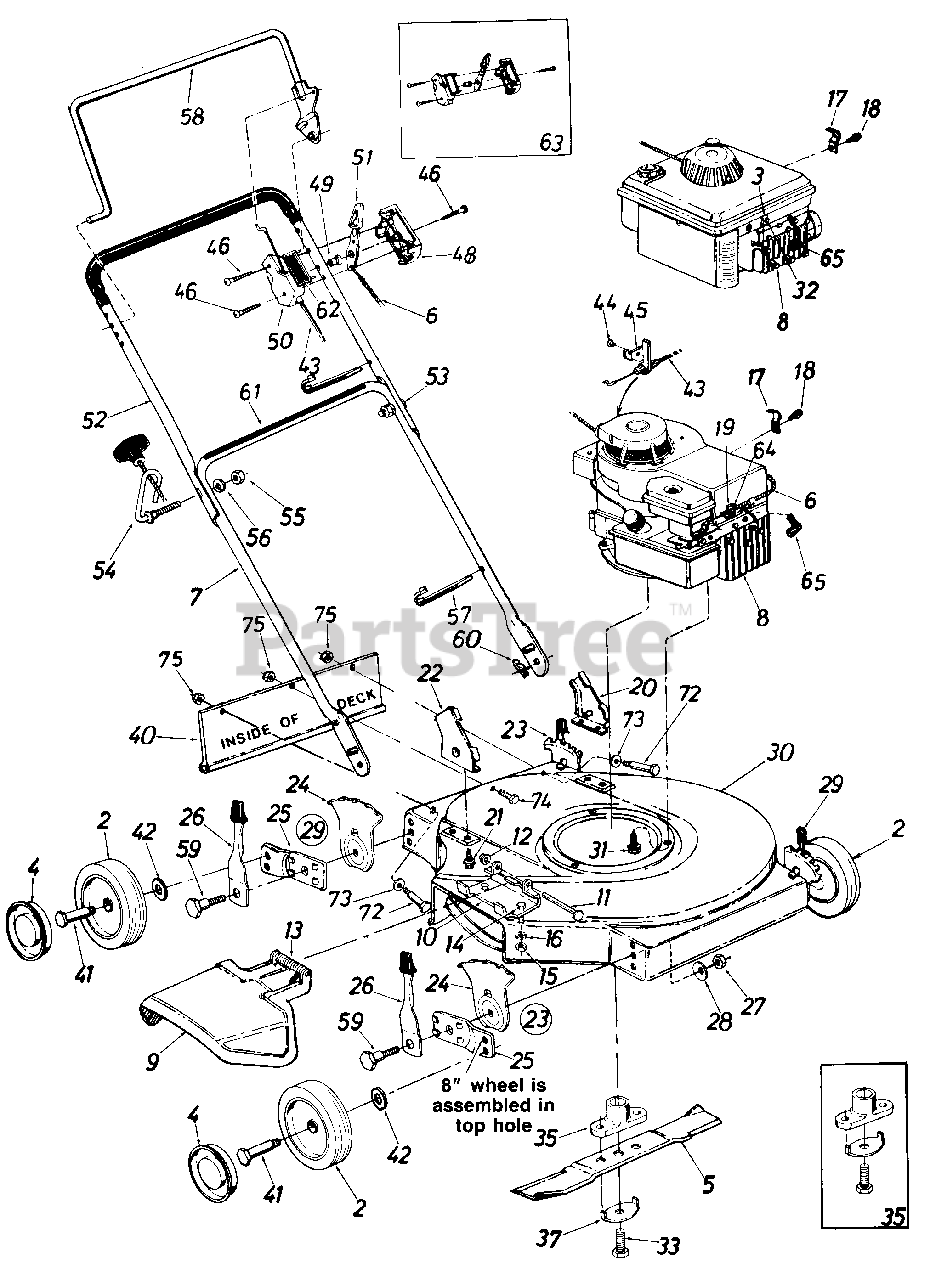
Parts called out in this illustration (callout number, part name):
2	Wheel Ass'y. Comp.
3	Cable Clamp
4	Hub Cap
5	20" Blade
6	Throttle Wire 53"
7	Lower Handle
8	Engine
9	Chute Deflector Ass'y. Comp.
10	Adapter Plate
11	Pivot Pin
12	Push Cap 1/4" Rod
13	Torsion Spring
14	Hex Bolt 1/4-20 x .50" Lg.
15	Hex Nut 1/4-20 Thd.
16	L-Wash. 1/4" I.D.
17	Cable Clip
18	Hex AB-Tap Scr. #10 x .38" Lg.
19	Casing Clamp
20	Handle Brkt. Ass'y. L.H.
21	Hex Wash. Hd. B-Tap Scr. 5/16-18 x .50" Lg.
22	Handle Brkt. Ass'y. R.H.
23	Height Adjuster Ass'y. Comp R.H.
24	Index Plate
26	Spring Lever Ass'y. w/Knob
27	Hex Nut 3/8-16 Thd.
28	Bell-Wash. .39" I.D. x 1.13" O.D.
29	Height Adjuster Ass'y. Comp. L.H.
31	Hex Wash. Hd. TT-Tap Scr. 3/8-16 x 1.0" Lg.
32	Hex B-Tap Scr. #10 x .62" Lg.
33	Hex Bolt 3/8-24 x 1.5" Lg.
35	Blade Adapter Kit
37	Blade Bell-Washer
40	Rear Flap Ass'y.
41	Axle Bolt
42	Bell-Wash. .40" I.D. x .88" O.D.
43	Control Cable 39"
44	Cable Brkt.
45	Pop Rivet
46	Truss. Mach. Self-Tap Scr. #12 x 1.5" Lg.
48	Control Panel Half
49	Control Disc Pin
50	Clutch Panel Half
51	Throttle Control Lever
52	Upper Handle
53	Curved Carriage Bolt 5/16-18 x 1.38" Lg.
54	Rope Guide Bolt
55	Hex Nut 5/16-18 Thd.
56	L-Wash. 5/16" I.D.
57	Cable Tie
58	Control Handle Ass'y. L.H.
59	Shld. Bolt .500" Dia. x .375
60	Hairpin Cotter
61	Instruction Label Handle
62	Control Label
63	Kit Control Housing Comp.
64	Hex Wash. Hd. AB-Tap Scr. #8 x .38" Lg.
65	Spark Plug Insulator
72	Shld. Bolt. 3/8" Dia. x 1.16" Lg.
73	Flat Wash. .28" I.D. x .75" O.D.
74	Hex Bolt 1/4-20 x .50" Lg.
75	Hex Ins. L-Nut 1/4-20 Thd.
